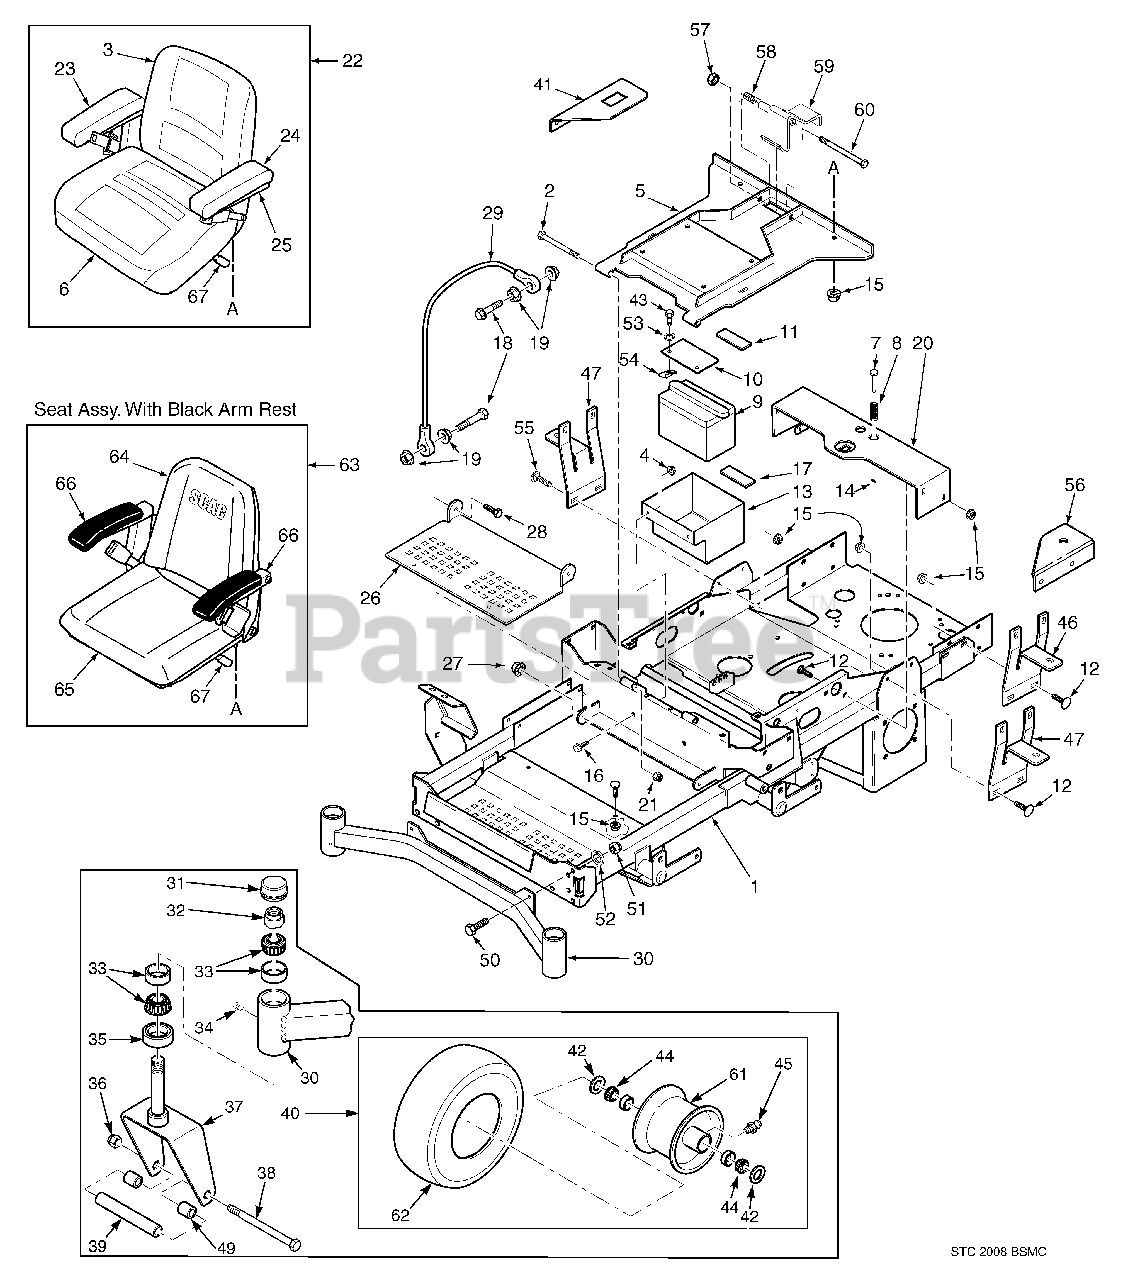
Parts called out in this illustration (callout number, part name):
1	Main Frame Assembly w/decals
2	Bolt, Hex Head 5/16-18 x 3-3/4"
3	Cushion, Back
4	Nut, Serr. Flange 3/8-16
5	Plate, Seat Mounting w/decals
6	Cushion, Lower Seat
7	Pin Retainer, Spring
8	Spring
9	Battery
10	Battery Cover
11	Battery Hold Down Pad
12	Bolt, Carr. 5/16-18 x 3/4"
13	Battery Box
14	Roll Pin, Spring 5/32 x 3/4"
15	Nut, Serr. Flange 5/16-18
16	Bolt, Hex Head 3/8-16 x 1"
17	Pad, Rubber
18	Bolt, Hex Head 1/4-20 x 1-1/4"
19	Nut, Serr. Flange 1/4-20
20	Seat Base Support
21	Nut, Elastic Stop 5/16-18
22	Seat Assembly w/ adj. rails
23	Arm Pad, RH
23	Bracket, Armrest RH
24	Arm Pad, LH
24	Bracket, Armrest LH
25	Channel, Armrest
26	Footplate
27	Nut, Elastic Stop 3/8-16
28	Bolt, Hex Head 3/8-16 x 1"
29	Cable, Seat Stop
30	Weldment, Caster Support
31	Cap, Grease
32	Nut, Elastic Stop 1.0-14
33	Bearing Set
34	Plug, 1/4-28
35	Seal, 2.0" OD x 1.625" ID
36	Nut, Elastic Stop 1/2-13
37	Yoke, Front Caster Wheel
38	Bolt, Hex Head 1/2-13 x 7-1/2"
38	Bolt, Hex Head 1/2-13 x 9-1/2"
39	Sleeve
40	Caster Wheel Assembly
41	Bracket, Hour Meter
43	Bolt, Hex Head 3/8-16 x 1-1/4"
44	Roller Bearing
45	Fitting, Grease
46	Mounting Bracket, Oil Tank
47	Mounting Bracket, Fuel Tank
48	Seat Pan
49	Spacer, Caster Wheel
50	Bolt, Hex Head 7/16-14 x 1-1/4"
51	Nut, Elastic Stop 7/16-14
52	Lockwasher, 7/16
53	Lock Washer. 3/8 Spring
54	U-Nut, 3/8-16
55	Bolt, Carriage 5/16-18 x 1"
56	Bracket, Fuel Valve
57	Lock Nut, 3/8-16 Center Lock
58	Spring, Seat Latch
59	Seat Latch Weldment
60	Bolt, Hex Head 3/8-16 x 6"
61	Rim
62	Tire, 13 x 5.0-6 Smooth
62	Tire, 13 x 6.5 Smooth
63	Seat Assembly w/ adj. rails
64	Cushion, Back
65	Cushion, Lower Seat
66	Arm rest Kit
67	Seat Adjustment Track Set
